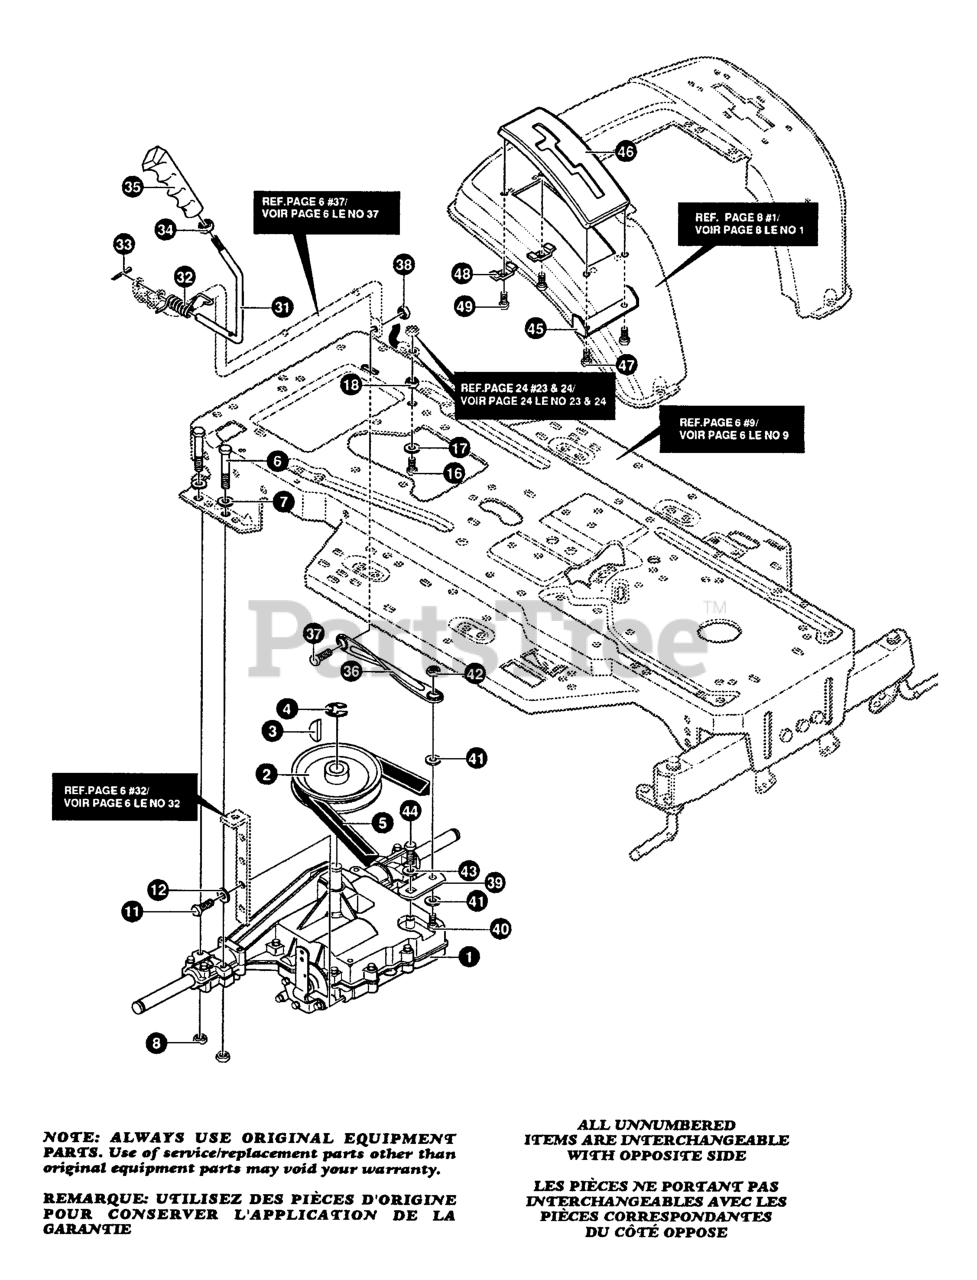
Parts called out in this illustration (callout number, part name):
1	TRANSAXLE **
4	RING, RETEX
5	BELT, V
7	WASHER
11	SCREW
12	WASHER
16	SCREW
17	WASHER
31	LEVER, SHIFT UPPER
32	SPRING, TORSION
33	PIN, COTTER
36	LINK, TIE ROD SHIFT
38	NUT
39	BRACKET, SHIFT
41	WASHER
42	NUT
44	SCREW
45	BRACKET COVER
46	COVER, PLASTIC
48	CLAMP, SPRING
